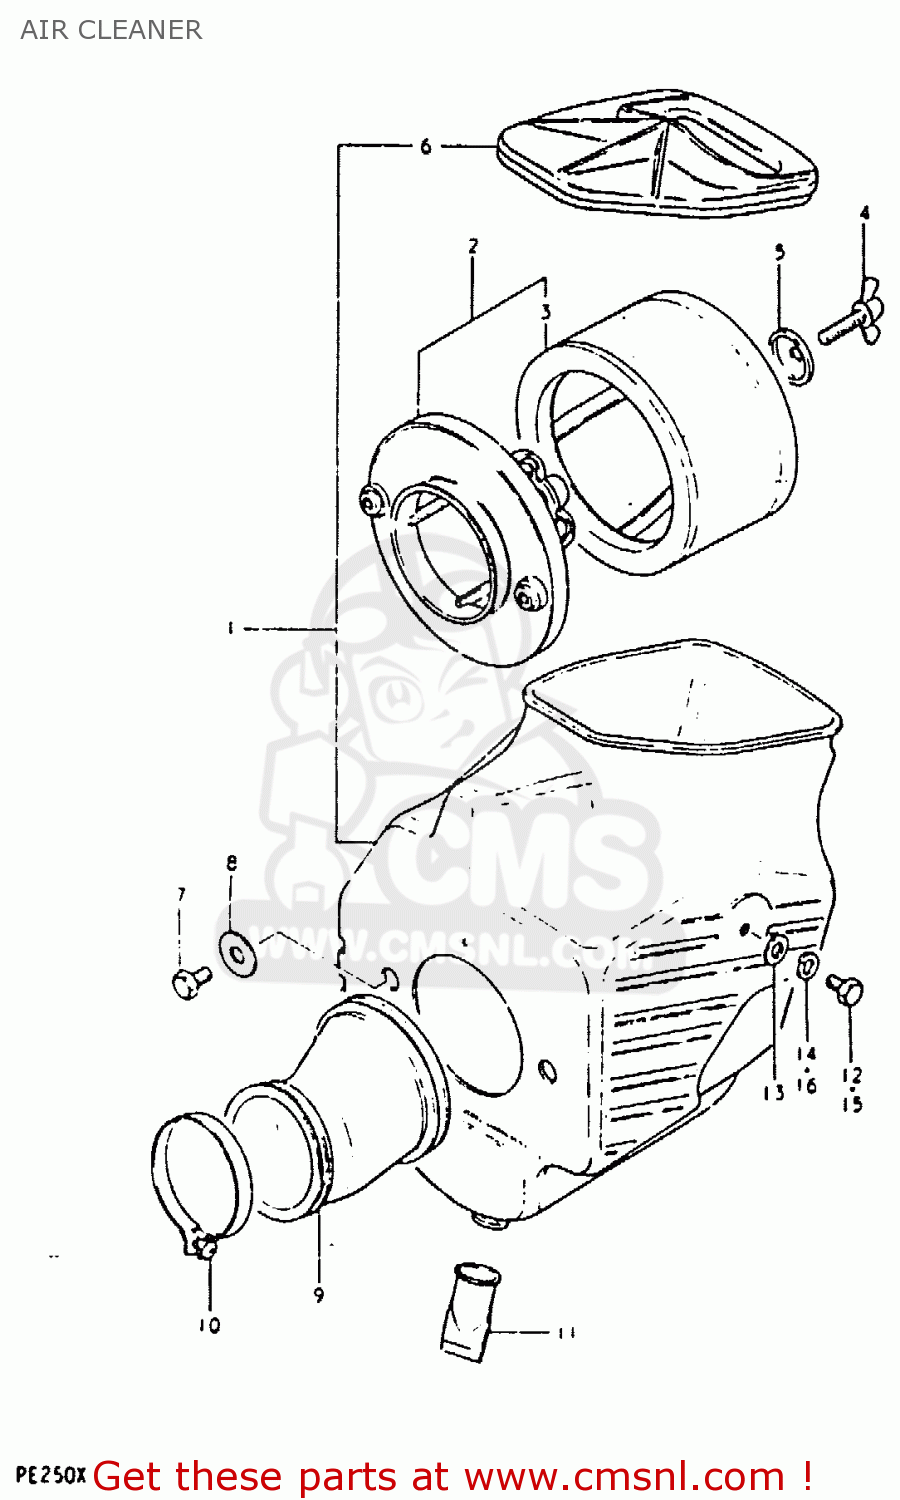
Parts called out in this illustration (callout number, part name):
1	CLEANER ASSEMBLY,AIR
2	FILTER ASSY
3	FILTER
4	WING BOLT,AIR CLEANER
5	HOLDER,FILTER
6	CAP
7	BOLT
8	SPACER,AIR CLEANER,REAR
9	TUBE,AIR CLEANER OUTLET
10	CLAMP
11	HOSE,AIR CLEANER DRAIN
12	BOLT
13	WASHER
14	LOCK WASHER
15	SCREW
16	LOCK WASHER
